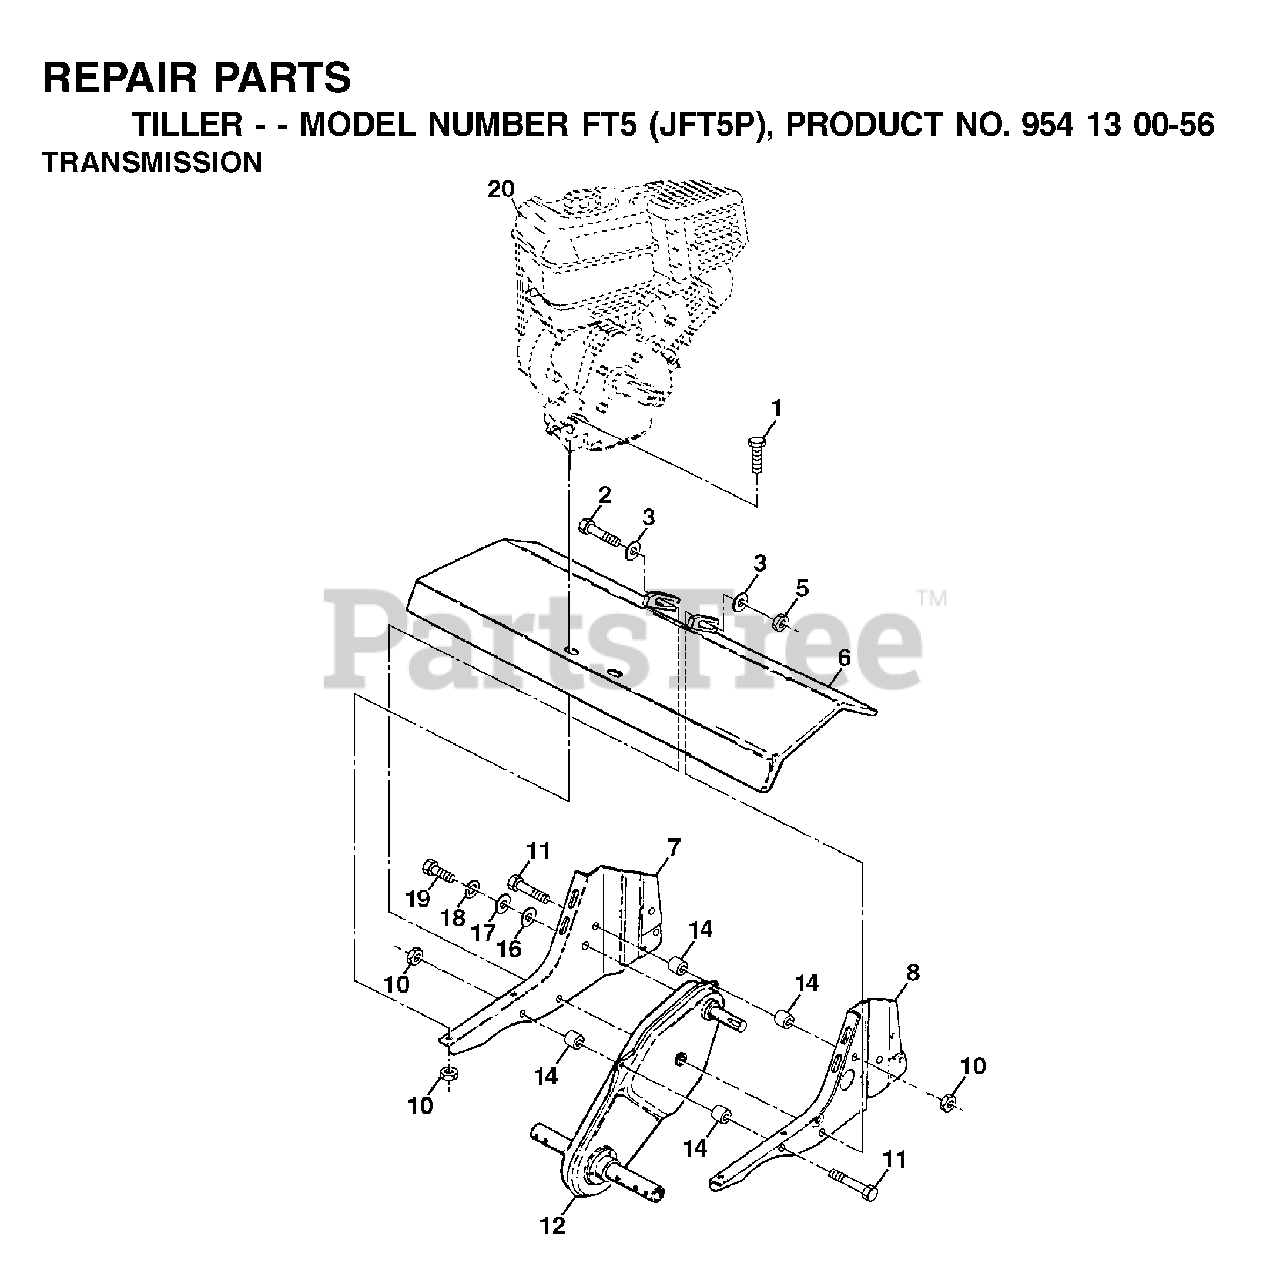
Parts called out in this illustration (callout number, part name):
1	BOLT
3	WASHER
5	NUT
10	LOCKNUT-FLANGE 5/16-18
11	BOLT
15	LOCKNUT-FLANGE 5/16-18
18	LOCKWASHER
